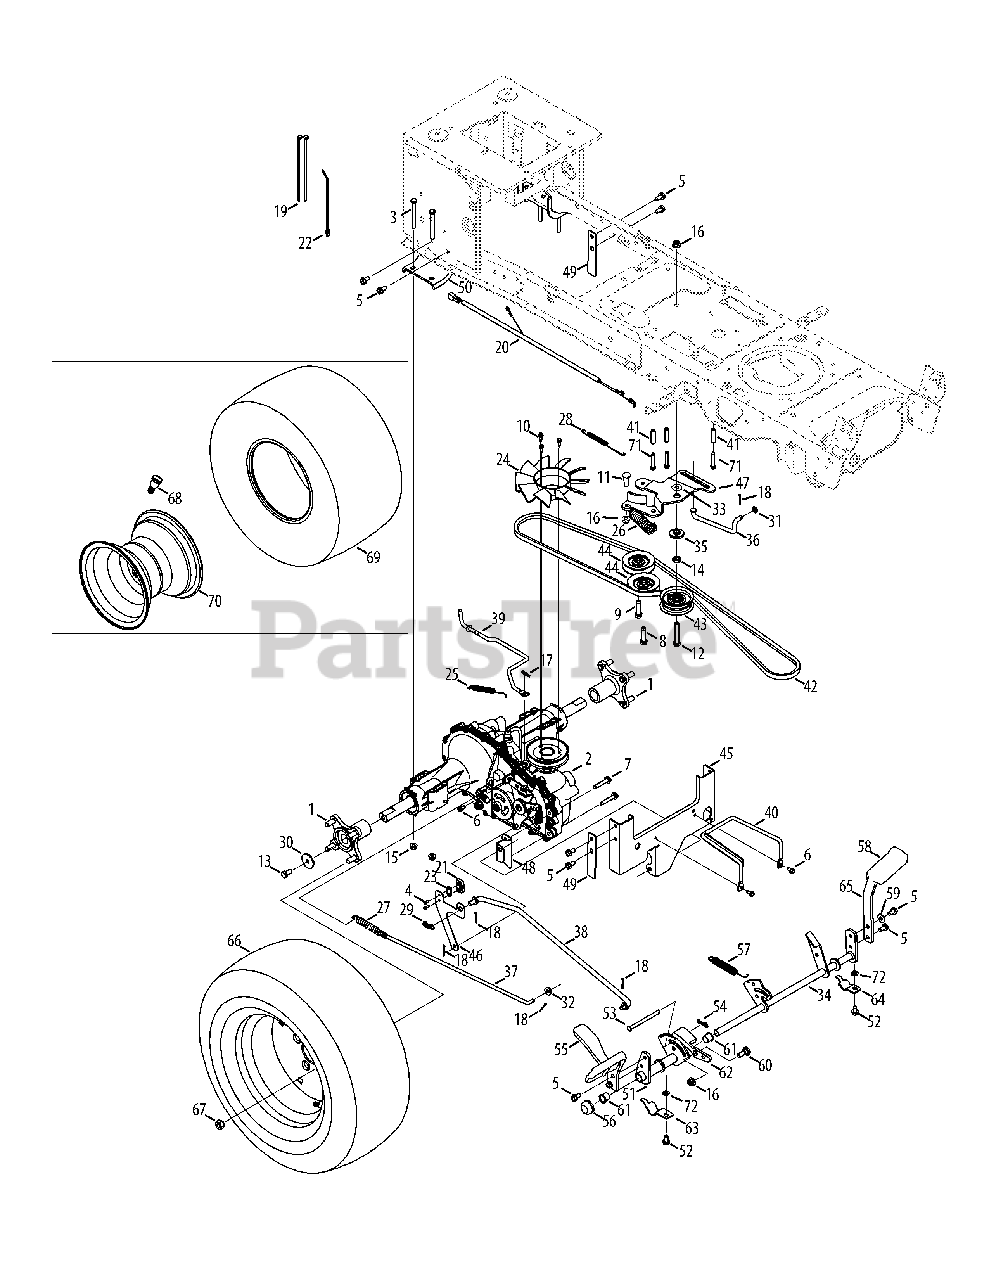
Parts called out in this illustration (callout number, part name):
1	Wheel Assembly Hub
2	Transmission
3	Hex Screw, 5/16-18:3.00
4	Screw, #8-18:0.500
5	Taptite Screw, 5/16-18:.750
6	Taptite Screw, 1/4-20:0.500
7	Taptite Screw, 5/16-18:1.750
8	Taptite Sems Screw, 3/8-16:1.500
9	Taptite Sems Screw, 3/8-16:1.875
10	Screw, #12-24:0.625
11	Scr, Shldr, .50 x .685 3/8-16
12	Hex Screw, 3/8-16:2.25
13	Hex Screw, 3/8-16:.750
14	Jam Nut, 7/16-20
15	Flangelock Nut, 5/16-18
16	Flangelock Nut, 3/8-16
17	Cotter Pin, .072 DIA. x 1.13 LG
18	Cotter Pin, 3/32:1.0
19	Cable Tie, 3/16 x .05 x 7.4
20	Jumper Harness
21	Short Spring Switch
22	Push Mount Cable Tie 7.5 LG
23	Insulator Nut Plate
25	Extension Spring, .50 DIA x 5.0 LG
26	Extension Spring, 1.00 DIA x 4.75
27	Extension Spring, .59 OD x 4.00 LG
28	Extension Spring, .38 DIA x 5.6
29	Extension Spring, .375 OD x 1.44 LG
30	Flat Washer, .390 x 1.500 x .134
31	Flat Washer, .330 x .630 x .0635
32	Flat Washer, .344 x .750 x .120
33	Washer, Flat, .385 x 1.0 x .030
34	Brake Control Assembly
35	Shoulder Spacer, 1.375 x .380 x .183
36	Footpedal Bypass Transmission Rod
38	Control Rod
39	Disengage Rod
40	Belt Keeper, 5/16
41	Spacer, 260 x .372 x 1.420 LG
42	V Belt, 4L x 77.0
43	Flat Idler Pulley, 2.75 OD
44	V Idler Pulley, 3.06
45	Torque Bracket
46	Switch Bracket
47	Center Idler Bracket
49	Plate Bracket
51	Hydro Pedal Bracket Assembly
52	Taptite Screw, 5/16-18:0.625
53	Clevis Pin, 5/16 x 3.985
54	Bow-Tie Cotter Pin
55	Control Pedal
57	Extension Spring, .63 DIA x 4.95 LG
58	Brake Pedal Pad
59	Bell Washer, .340 x .872 x .060
60	Shoulder Bolt, .500 x .270:3/8-16
61	Flange Bearing, .630 ID x .695 OD x .60
62	Cruise Latch
63	Pedal Support Bracket
64	Pedal Support Bracket, 5/8
65	Brake Pedal Bracket
66	Wheel Assembly
67	Lug Nut, 7/16-14
68	Air Valve
70	Rim Assembly
71	Taptite Screw, 1/4-20:1.750
72	Washer, Flat, .344 x .688 x .065
